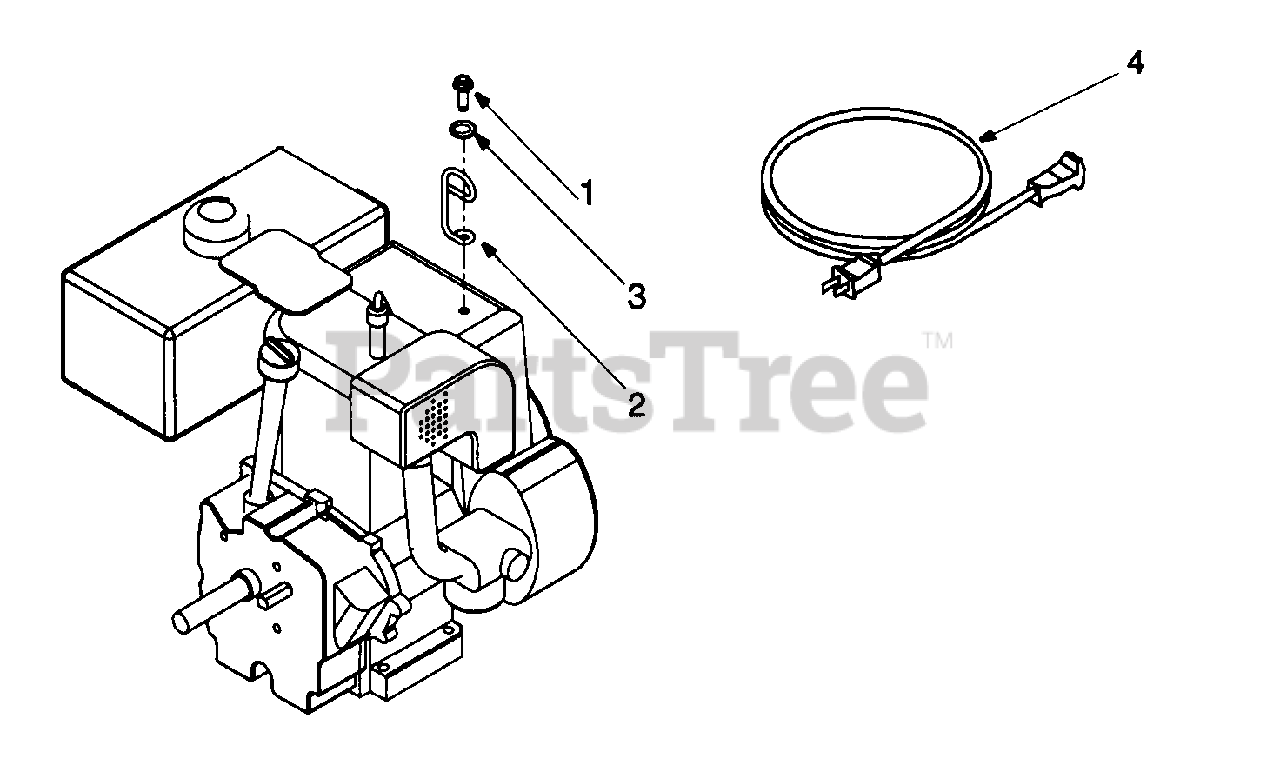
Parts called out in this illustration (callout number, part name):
1	Hex Lock Nut: 1/4-20
2	Cable Guide
3	Flat Washer
4	Extension Cord: 110V, 3-prong
